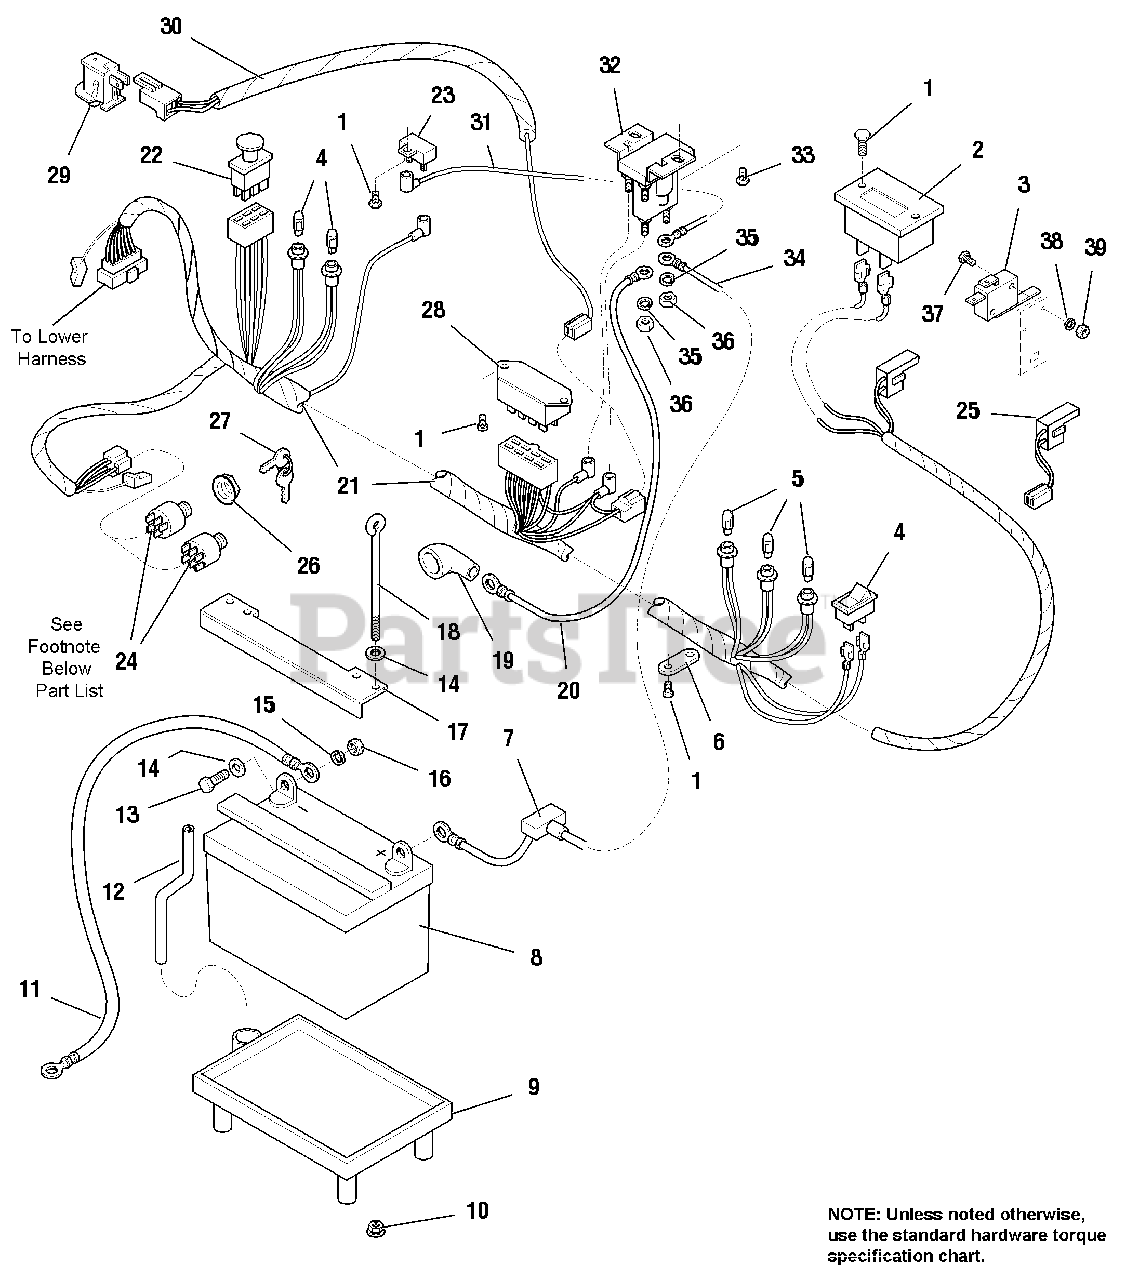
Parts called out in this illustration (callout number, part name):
1	CAPSCREW, Plastite, #8-16 x 1/2
3	INTERLOCK SWITCH, Cruise/Parking Brake
4	SWITCH, Headlight
5	BULB, Indicator Light
6	STRAP, Wire Retainer
7	BOOT, Insulator
9	TRAY, Battery
10	NUT, Plastic, 1/4-20
11	CABLE, Battery to Ground
12	HOSE, Battery, Drain
13	CAPSCREW, Hex Hd, 1/4-20 x 3/4
14	WASHER, Plain, 1/4
15	LOCKWASHER, 1/4
16	NUT, Hex, 1/4-20 UNC
17	HOLD DOWN, Battery
18	ROD, Battery Hold Down
19	COVER, Terminal
20	CABLE, Solenoid to Starter
21	WIRE HARNESS, Main
22	SWITCH, PTO Electric Clutch
23	CIRCUIT BREAKER
24	IGNITION SWITCH, 5-Pin Plastic Body
24	IGNITION SWITCH, 6-Pin, Plastic Body
25	WIRE ASSY, Lock Light
26	NUT, Flange
27	KEY, Ignition
29	SWITCH, Interlock, Clutch/Brake Pedal
32	SOLENOID
33	CAPSCREW, Hex Washer Hd, Plastite, 1/4-20 x 1/2
34	CABLE, Battery to Solenoid
35	LOCKWASHER, 5/16
36	NUT, Hex, 5/16-24
37	CAPSCREW, Taptite, #5-40 x 3/4
38	LOCKWASHER, 1/8
39	NUT, Machine Screw, #5-40
